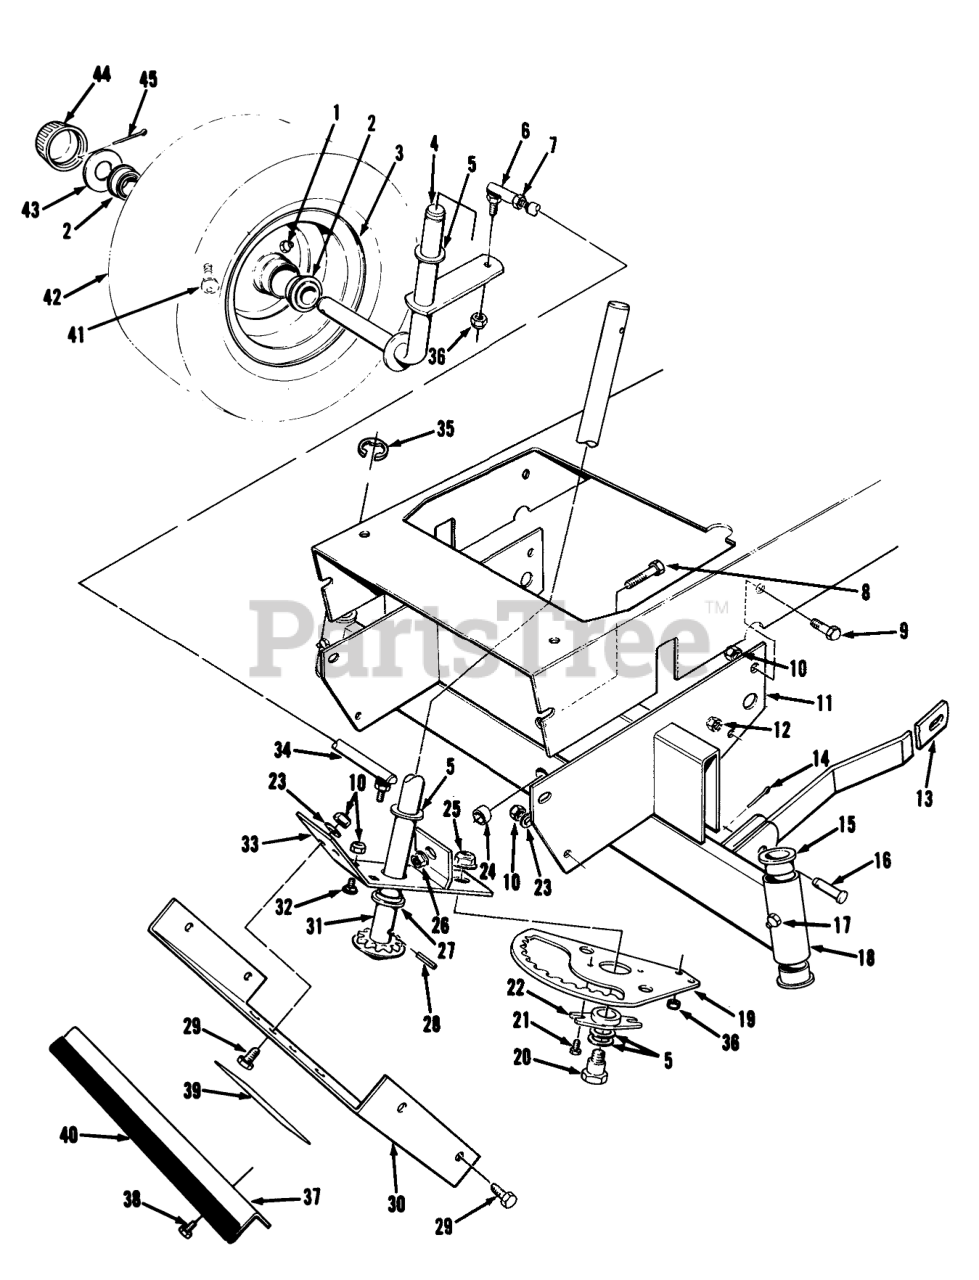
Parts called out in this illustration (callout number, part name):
1	FITTING-GREASE
2	Bearing
4	Spindle RH
5	WASHER-THRUST
6	JOINT-BALL
7	NUT-JAM
8	SCREW-HH
9	SCREW-HH
10	NUT-LOCK, NI
11	Support
12	NUT-LOCK, CONE
13	Arm-Suspension, Front
14	PIN-COTTER
15	BEARING-FLANGE
16	PIN-CLEVIS
17	GREASE FITTING
18	Axle (Includes Reference # 15 & 17)
19	STEERING RACK B
21	SCREW-HWH
22	BUSHING-SECTOR
23	WASHER-PLAIN
24	SPACER-AXLE, FRONT
25	NUT-HF
26	NUT-HF
27	BEARING-FLANGE
28	PIN-ROLL, SLOTTED
29	SCREW-HH
30	Cover-Front
31	STRG SHAFT WA
32	SCREW-CARR
33	Bracket-Steering Rack (Includes Reference #27)
34	Tie Rod (Includes Reference # 35 & 36)
35	E-RING
36	NUT-LOCK
37	FRONT GUARD R
38	SCREW-HWHTF
39	Decal-Warning
40	TRIM-FRONT GUARD
41	STEM-VALVE
42	TIRE,PNEU.11X4.00X5
43	WASHER-PLAIN
44	CAP-HUB
45	PIN-COTTER
